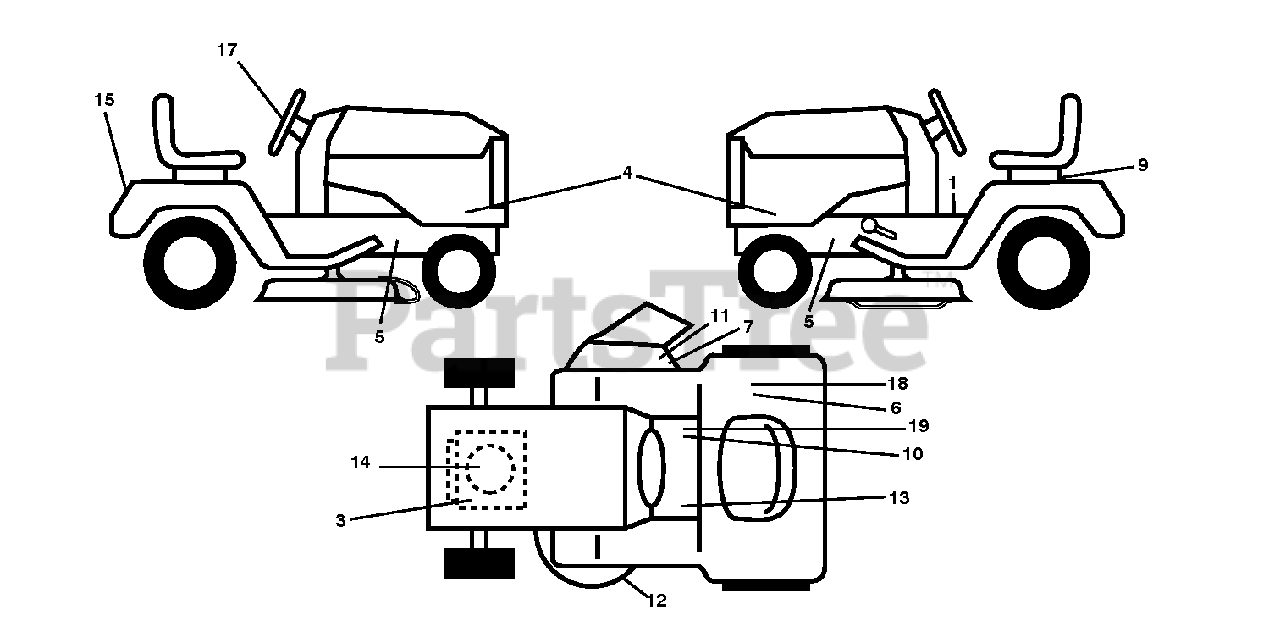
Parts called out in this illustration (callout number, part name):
6	DECAL.80 DBA.AUSTRALIA
7	DECAL, DEFLECT WARNING
9	DECAL BTRY SYMBOLS
10	DECAL PARK BRAKE
11	DECAL.INTERNATIONL.CUTFINGER
12	DECAL.V-BELT.SCHEMATIC.36/38/9
